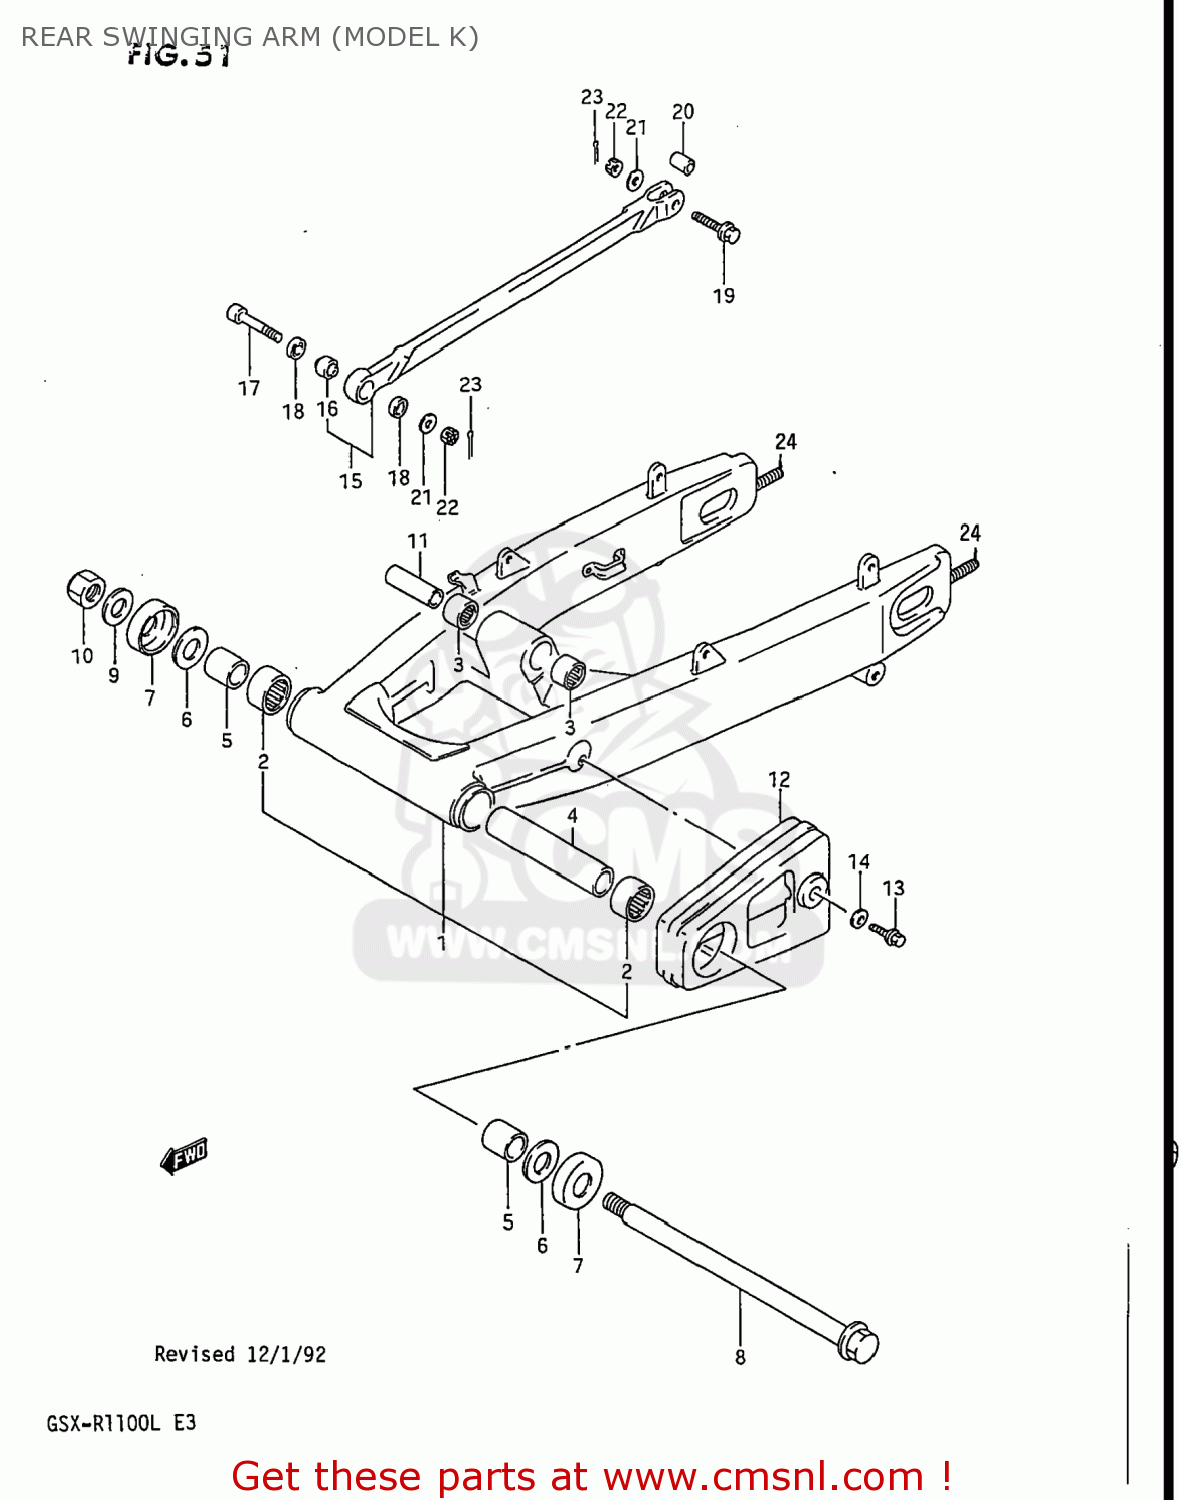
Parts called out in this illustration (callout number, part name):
1	SWING ARM ASSEMBLY,REAR
2	BEARING(25X33X30)
3	BEARING(20X27X23.5)
4	SPACER,RR SWGARM PIVOT CTR
5	SPACER,RR SWGARM PIVOT BERRING
6	WASHER
7	DUST SEAL,RR SWGARM PIVOT
8	SHAFT,REAR SWING ARM PIVOT
9	WASHER
10	NUT
11	SPACER,RR CUSHION LEVER
12	BUFFER,CHAIN TOUCH DEFENCE
13	BOLT
14	WASHER
15	TORQUE LINK SET,REAR
16	SPHERICAL BEARING,TORQUE
17	BOLT(8X48)
18	19
19	BOLT
20	SPACER,RR TORQUE LINK RR
21	WASHER
22	NUT 8MM
23	PIN 20X20
